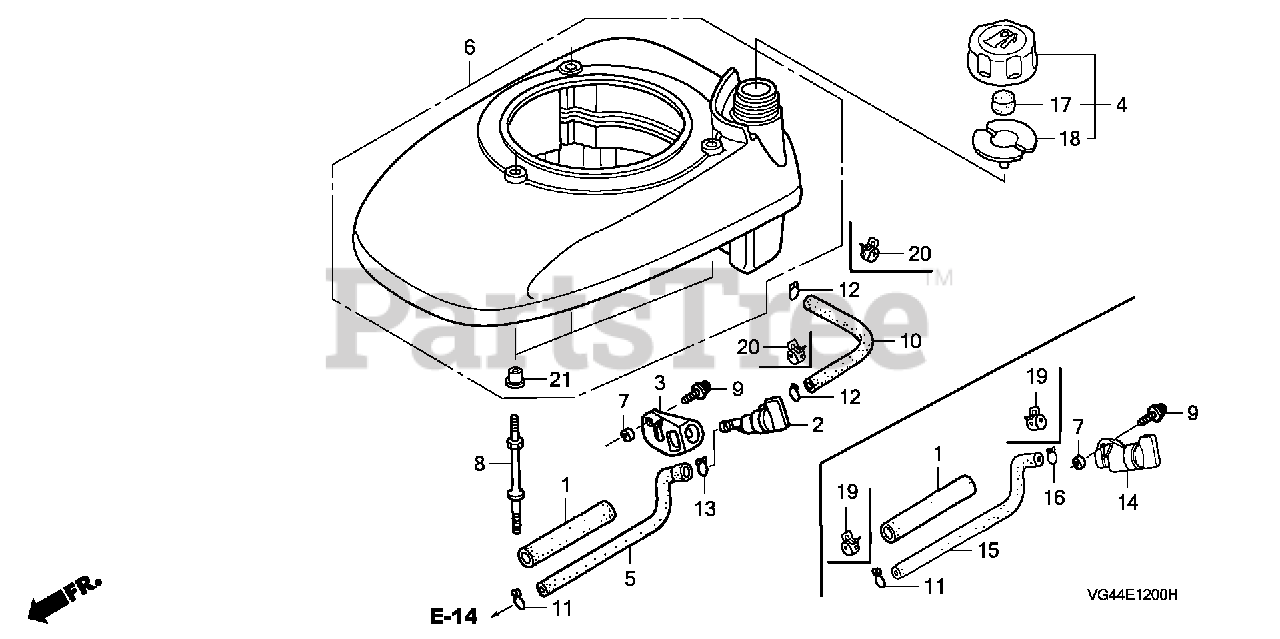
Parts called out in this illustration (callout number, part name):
1	RUBBER, SUPPORTER (107MM)
2	PETCOCK ASSY.
3	BRACKET, PETCOCK
4	CAP ASSY., FUEL TANK
5	TUBE, FUEL
6	COVER KIT, FAN
6	COVER, FAN *R8* (BRIGHT RED)
7	COLLAR, FR. TURN SIGNAL
8	BOLT, STUD (H=42.5MM)
9	SCREW-WASHER (5X10)
10	BULK HOSE, FUEL (5.5X3000) (5.3X150)
10	TUBE, FUEL TANK
10	TUBE, FUEL (5.3X150) (FKM)
11	CLIP, TUBE (B8)
12	CLIP, TUBE (B10)
13	CLIP, TUBE (C9)
14	PETCOCK ASSY.
15	TUBE, FUEL
15	TUBE, FUEL (FKM)
16	CLIP, TUBE (B8)
17	SPONGE, FUEL CAP BREATHER
18	GASKET, FUEL CAP
19	CLAMP, TUBE (D8)
20	CLAMP, TUBE (D10)
21	COLLAR, FAN COVER
